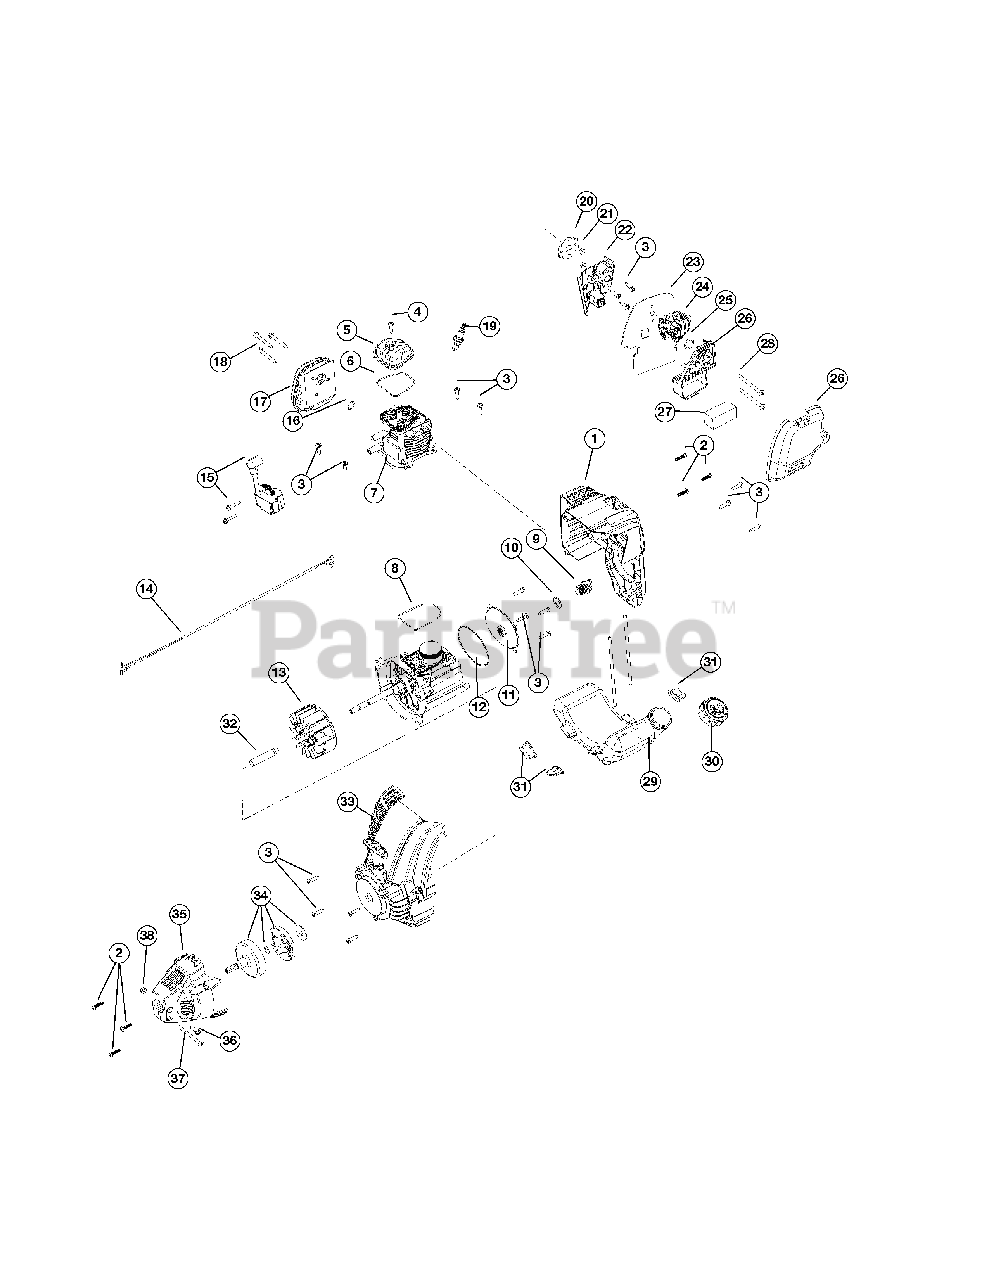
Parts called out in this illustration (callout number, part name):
1	Engine Cover Assembly
2	Cover Screw
3	Housing Screw
4	Rocker Cover Screw
5	Rocker Cover
6	Rocker Cover O-Ring
7	Cylinder Assembly
8	Cylinder O-Ring
9	Oil Plug
10	Oil Plug O-Ring
11	Crankcase Cover
12	Crankcase Cover O-ring
13	Flywheel Assembly
14	Lead Wires
15	Module Assembly
16	Muffler Gasket
17	Muffler Assembly
18	Muffler Screw
19	Spark Plug
20	Insulator Gasket
23	Carburetor Gasket
24	Carburetor
26	Air Cleaner Cover Assembly
27	Air Filter
29	Fuel Tank Assembly w/Fuel Lines
31	Fuel Tank Pads
33	Starter Housing Assembly
34	Clutch Assembly
35	Clutch Cover
36	Anti-Rotation Screw
37	Clamp Screw
